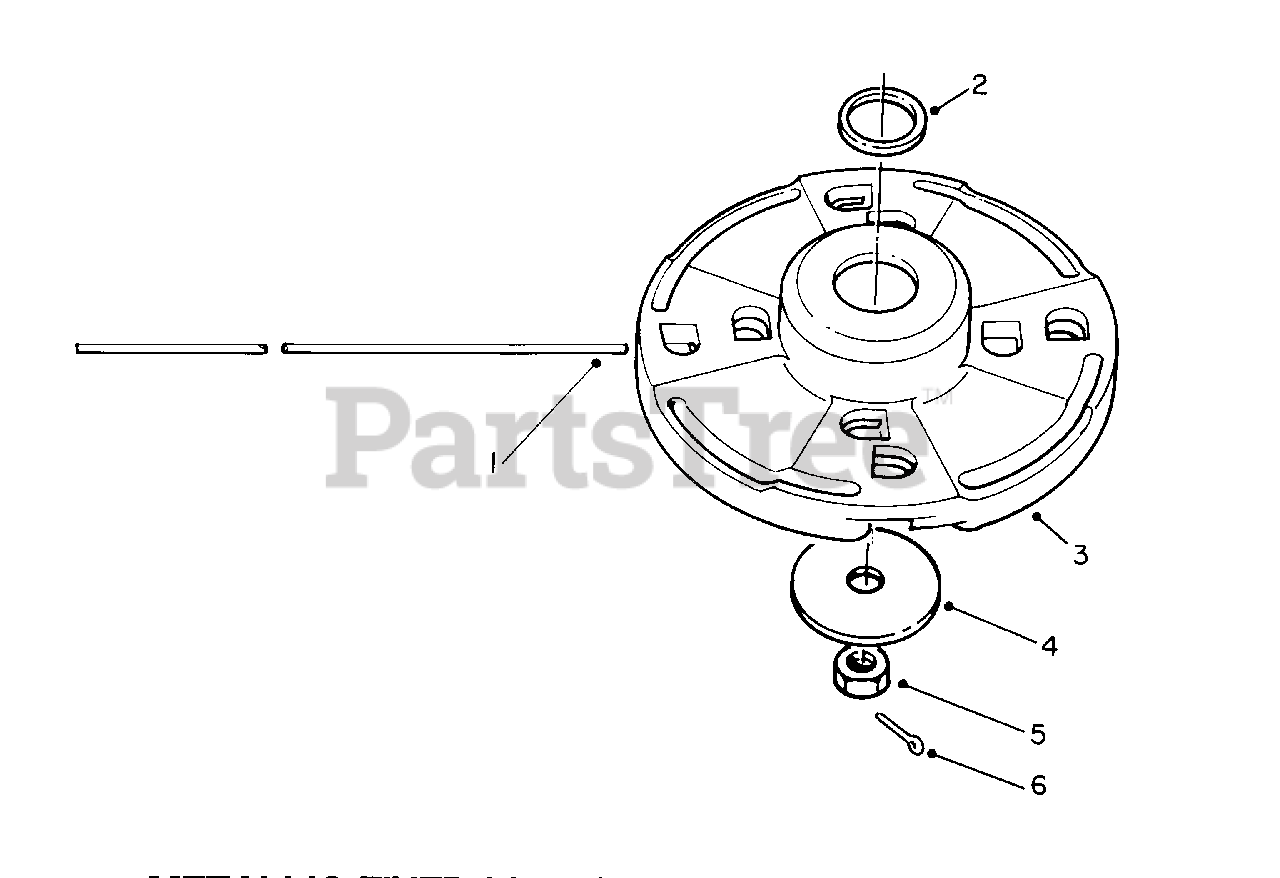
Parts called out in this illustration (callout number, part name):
1	Line-Cutting .105 Dia.
3	Cutter Head Assembly (Incl. Ref. #2)
4	Washer-Plate
5	Nut-Hex. L.H.
6	Pin-Cotter
